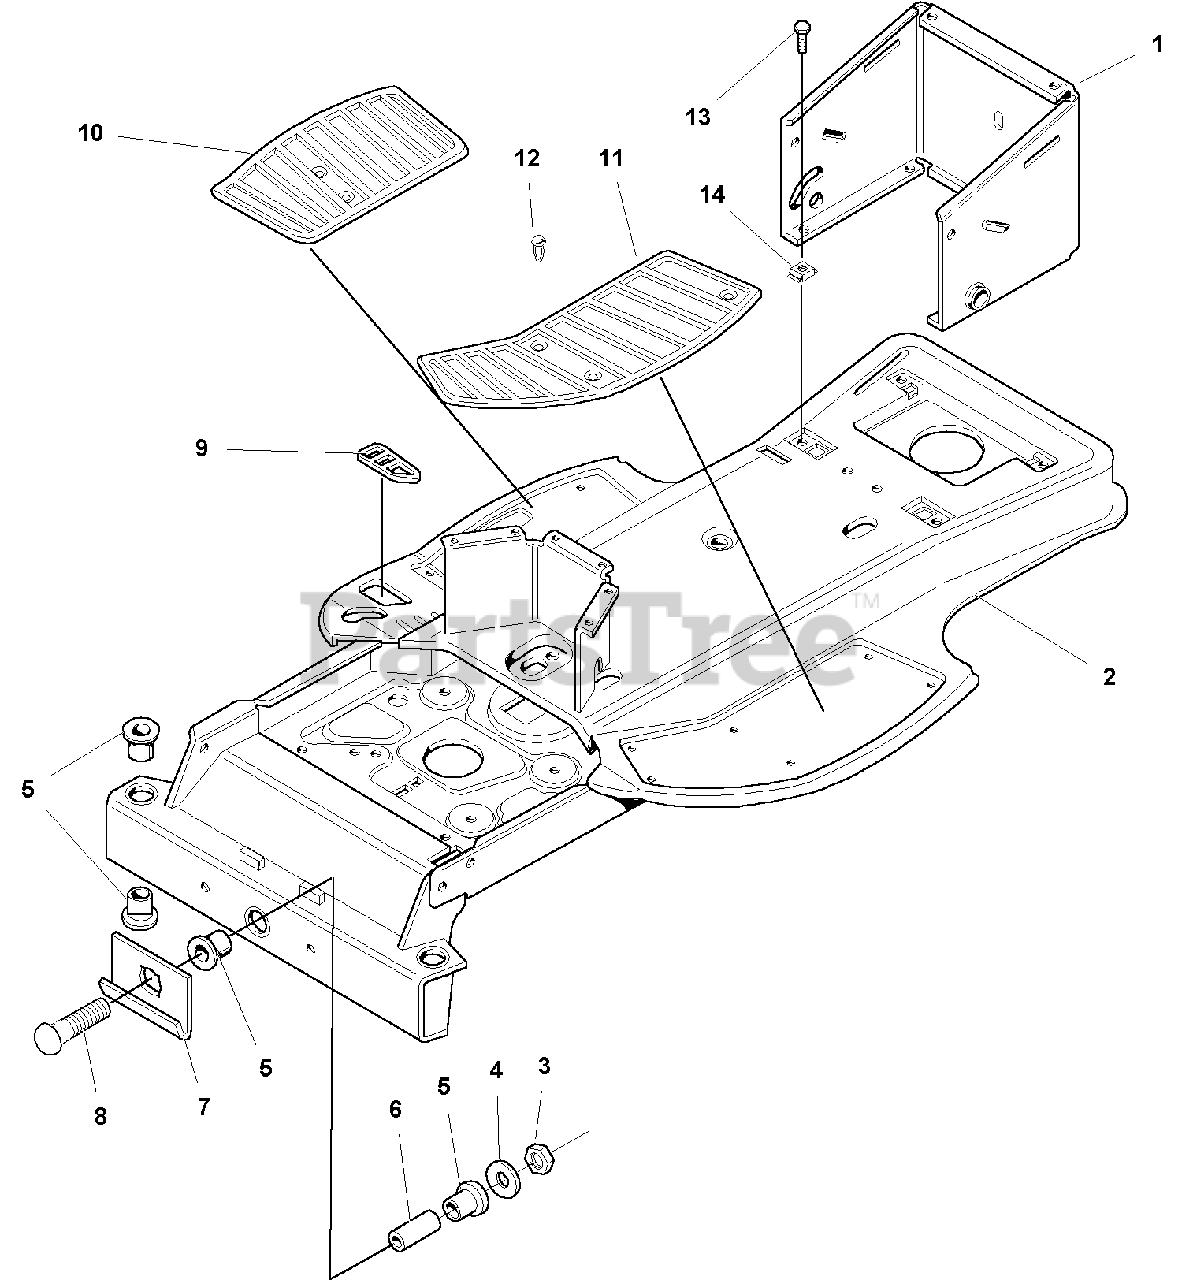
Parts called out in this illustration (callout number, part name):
1	WRAPPER, Rear Frame
2	FRAME ASSEMBLY
3	NUT, Hex Nylon Lock, 3/8-16
4	WASHER, 3/8
8	CARRIAGE BOLT, 3/8-16 x 3-1/4
10	PAD, Footrest, RH
11	PAD, Footrest, LH
12	FASTENER, Plastic, Ratchet
13	CAPSCREW, Hex Head Whiz Lock, 5/16-18 x 3/4
14	SPEED NUT, Tinnerman Lug Type, 5/16-18
